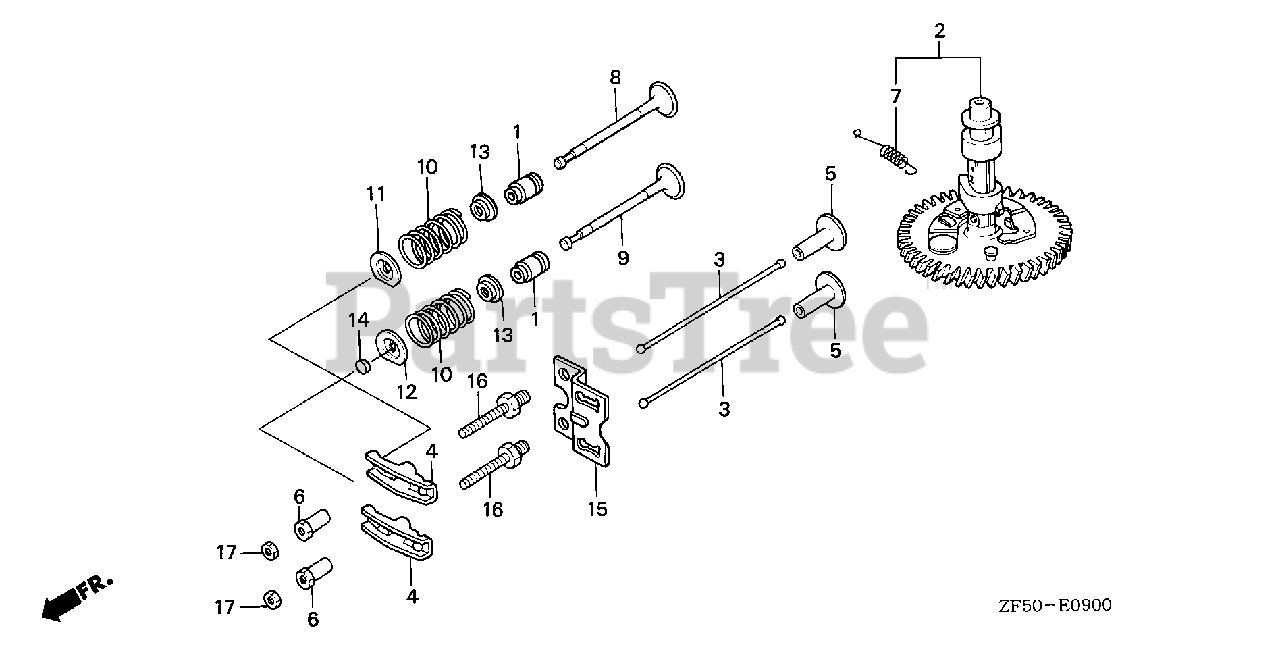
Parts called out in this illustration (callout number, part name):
1	SEAL, VALVE STEM
2	CAMSHAFT ASSY.
2	CAMSHAFT
3	ROD, PUSH
4	ARM, VALVE ROCKER
5	LIFTER, VALVE
6	PIVOT, ROCKER ARM
7	SPRING, WEIGHT RETURN
8	VALVE, IN.
9	VALVE, EX.
10	SPRING, VALVE
11	RETAINER, IN. VALVE SPRING
12	RETAINER, EX. VALVE SPRING
13	SEAT, VALVE SPRING
14	ROTATOR, VALVE
15	GUIDE, PUSH ROD
16	BOLT, PIVOT (8MM)
17	NUT, PIVOT ADJUSTING
